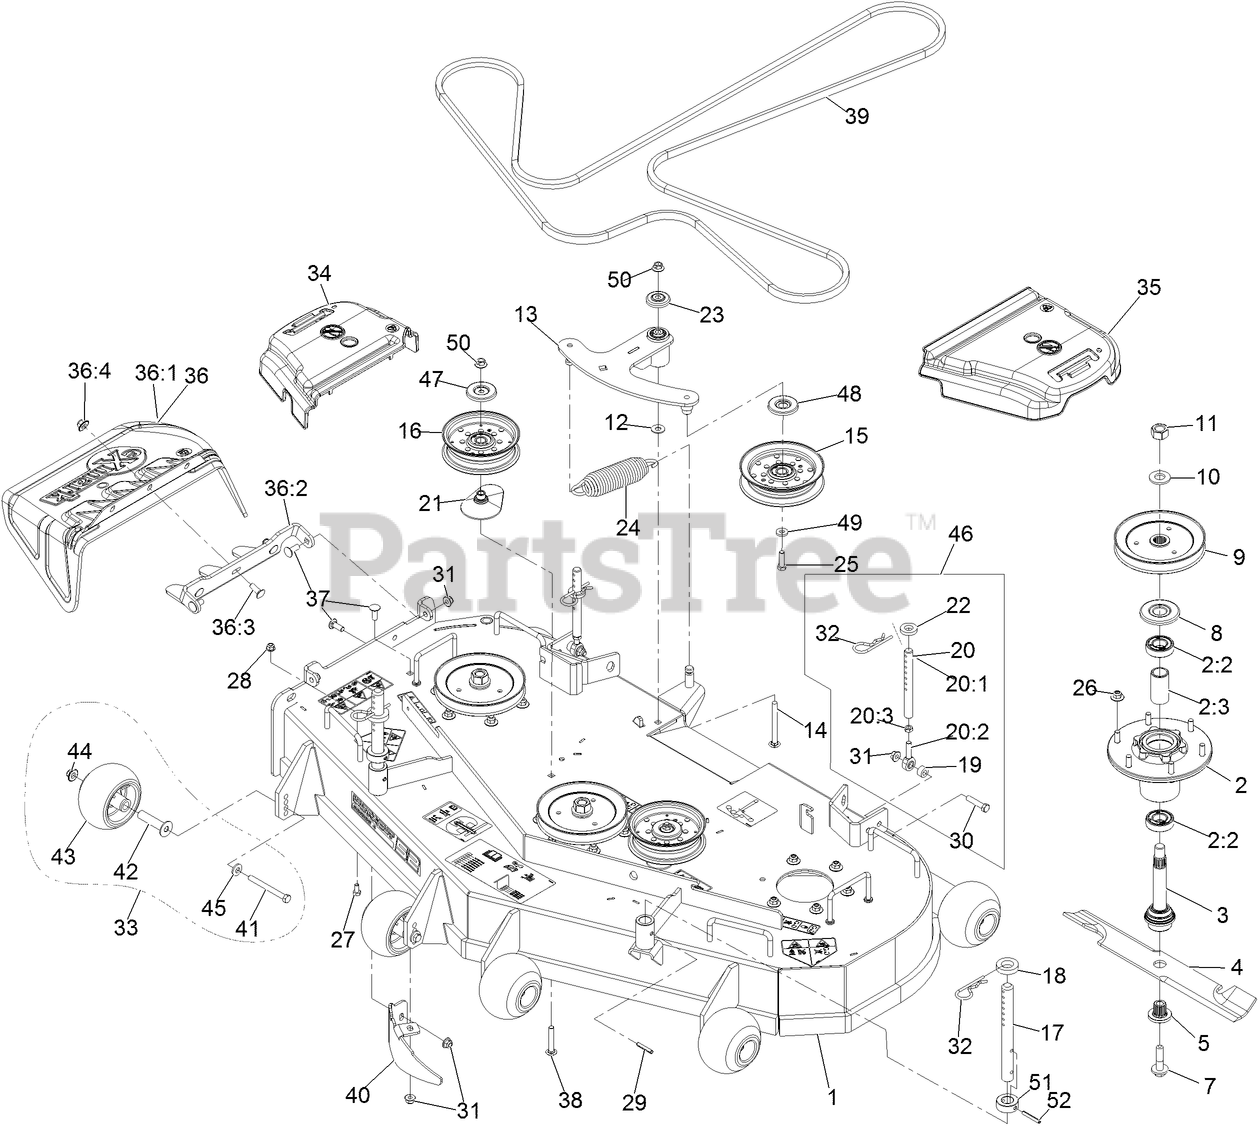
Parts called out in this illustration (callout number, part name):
1	ASM, DECK W/ DECALS, 52
2	ASM-CUTTER HSG WITH BEARINGS
2:2	BEARING-BALL
2:3	SPACER-BEARING
3	ASM-SPINDLE AND SEAL
5	BUSHING,SPLINED
7	SCREW,SEMS 1/2-20 X 2.19
8	GUARD,BEARING TOP .989
9	SHEAVE,BLADE DRIVE 6.50
11	NUT-HEX
12	WASHER-FLAT
13	ASM, DECK IDLER
14	SCREW-CARR
15	IDLER-PULLEY, FLAT
16	IDLER-PULLEY, FLAT 5.00X1
17	ROD, DECK SUPPORT
18	SPACER-DECK SUPPORT
20:1	LINK,SUPPORT
20:2	BALLJOINT
20:3	NUT-HJ
21	SPACER-PULLEY
23	GUARD-TOP
24	SPRING-EXTENSION
25	SCREW-HH
26	Nut-Nyloc 3/8-16 Flg
27	SCREW-HH
28	NUT-HF, NI
30	SCREW-HH
31	NUT-HF, NI
32	PIN,HAIR COTTER
33	KIT, ANTI-SCALP ROLLER
34	COVER-BELT, RH
35	COVER-BELT, LH
36	ASM,DISCHARGE CHUTE
36:1	CHUTE,DISCHARGE
36:2	BRACKET,DISCHARGE CHUTE
36:3	SCREW-CARR
36:4	Nut-Nyloc 3/8-16 Flg
37	SCREW-CARR
38	BOLT-CARR, SHORT NECK
39	BELT, DECK DRIVE
40	BAFFLE-DOGLEG, LZ-VT52
41	SCREW-HH 3/8-16 X 3 3/4 GR 8
42	AXLE, ROLLER
43	ROLLER-SCALP, ANTI
44	Nut-Nyloc 3/8-16 Flg
45	WASHER-BELLEVILLE
46	KIT,SUPPORT LINK W/PIN
47	SHIELD-DUST
48	SHIELD-GUARD, DUST
51	COLLAR, DECK HEIGHT PIN
52	PIN-ROLL
